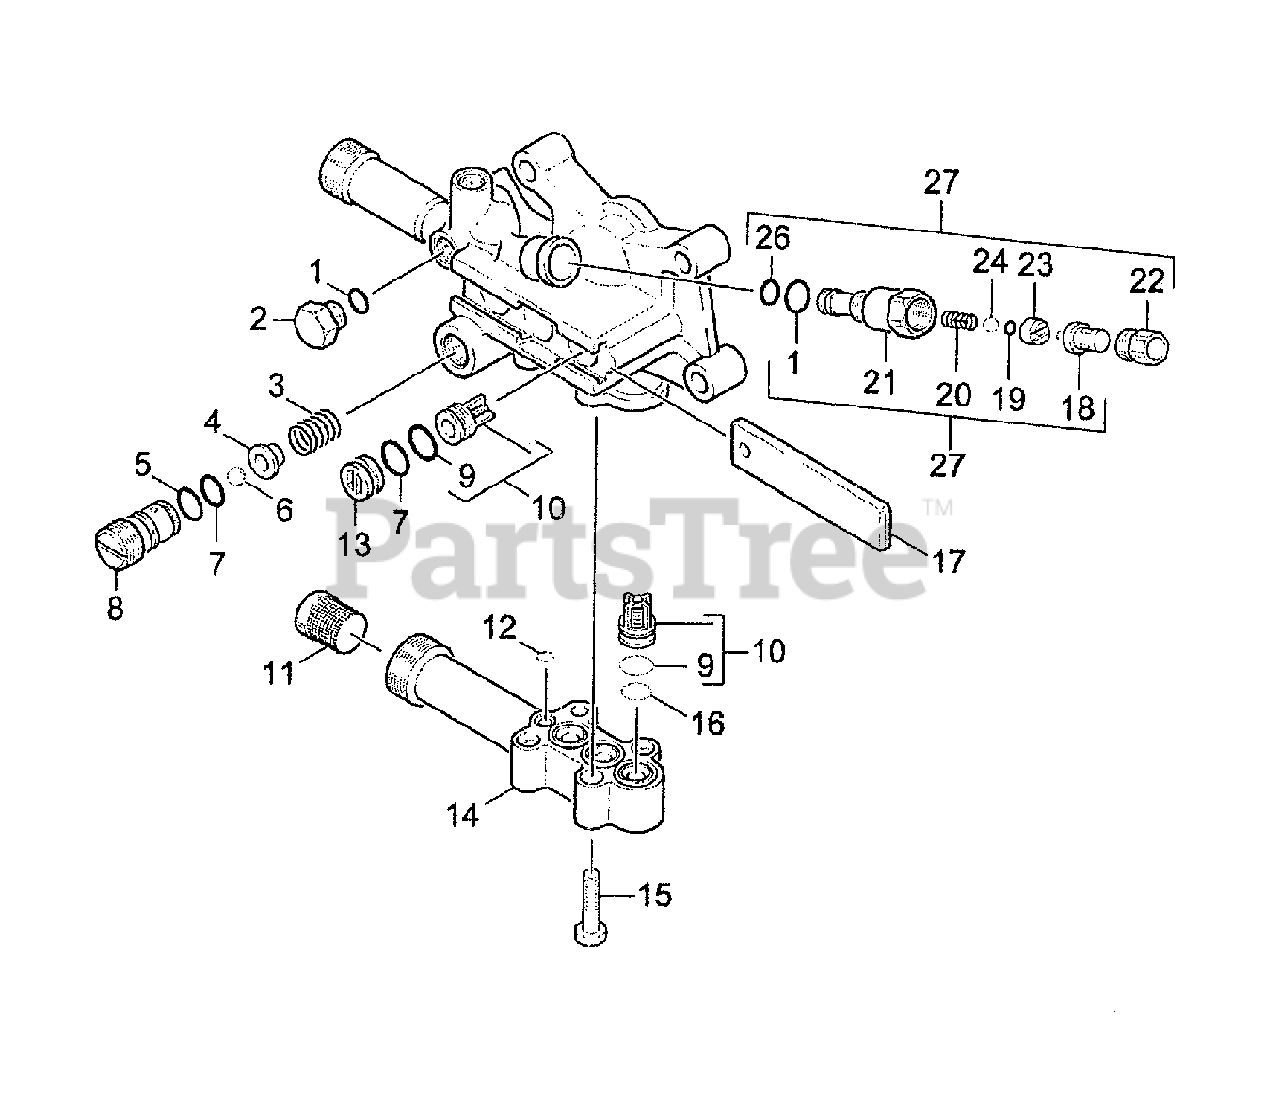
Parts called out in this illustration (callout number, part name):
2	Closing Screw
3	Helical Spring
8	Valve Screw
20	Helical Spring
21	Union Screw
22	Closing Screw
